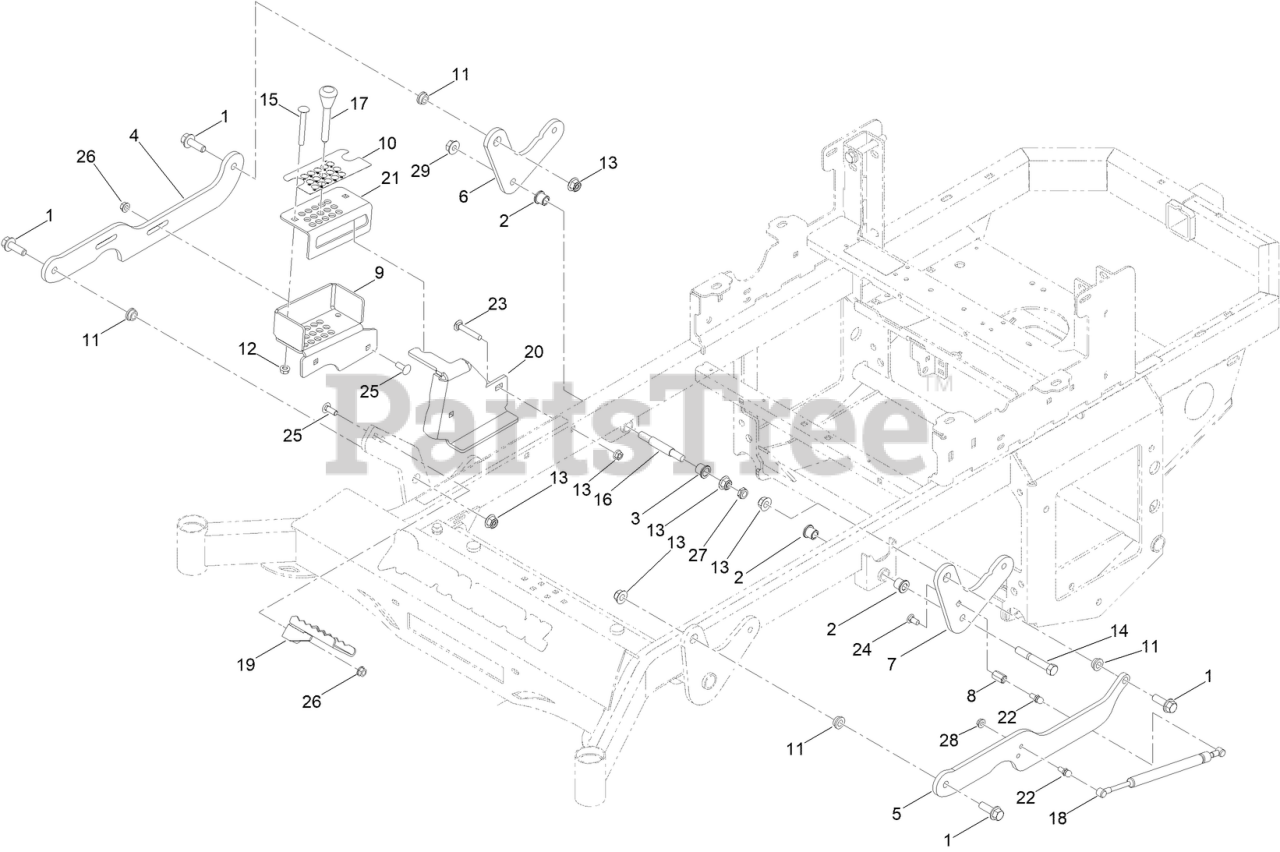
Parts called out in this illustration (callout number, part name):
1	SCREW-HHF
2	BUSHING-FLANGE
3	BUSHING-FLANGE
4	2024 DECK HEIGHT ARM RT LINK
5	LINK-DECKLIFT
6	ARM-DECKLIFT REAR (3/8")
7	ARM-DECKLIFT REAR (3/8")
8	HEX COUPLING NUT - REDUCER (3/8" TO 5/16
9	BRACKET PIN SYSTEM (BOTTOM) PAINTED GREY
10	DECAL-HEIGHT OF CUT
11	1/2IN ID X 3/4IN OD X 3/8IN FLANGE BUSH
13	1/2-13 HEX FLANGE 2-WAY REV CNTR L/NYZ
14	1/2-13 X 3-1/2 HEX C/S GR 5 ZINC YELLOW
15	(3/8-16 X 3 CARRIAGE BOLT (GR.5) ZC/YEL)
16	RR DECK HEIGHT BOLT (MACHINED)
17	MAGNETIC PIN FOR STAND ON MWR
18	DECK ASSIST GAS SPRING
19	MWR DECK HEIGHT FOOT PEDAL PAINT
20	2022 DECK LOCK PIN TUBE BRKT
21	2022 DHI PIN ARM LINK TOP BRKT
22	5/16-18X1.286 DAMPER BALL STUD (.562 TL)
23	SCREW-CARR
24	3/8 X 3/4IN GR 8 CARR BOLT ZINC
25	3/8-16 X 1 CARRIAGE BOLT YZ GR.8
26	3/8-16 HEX FLANGE NUT W/SERR ZINC YELLOW
27	NUT-HEX
29	NUT-HHF
